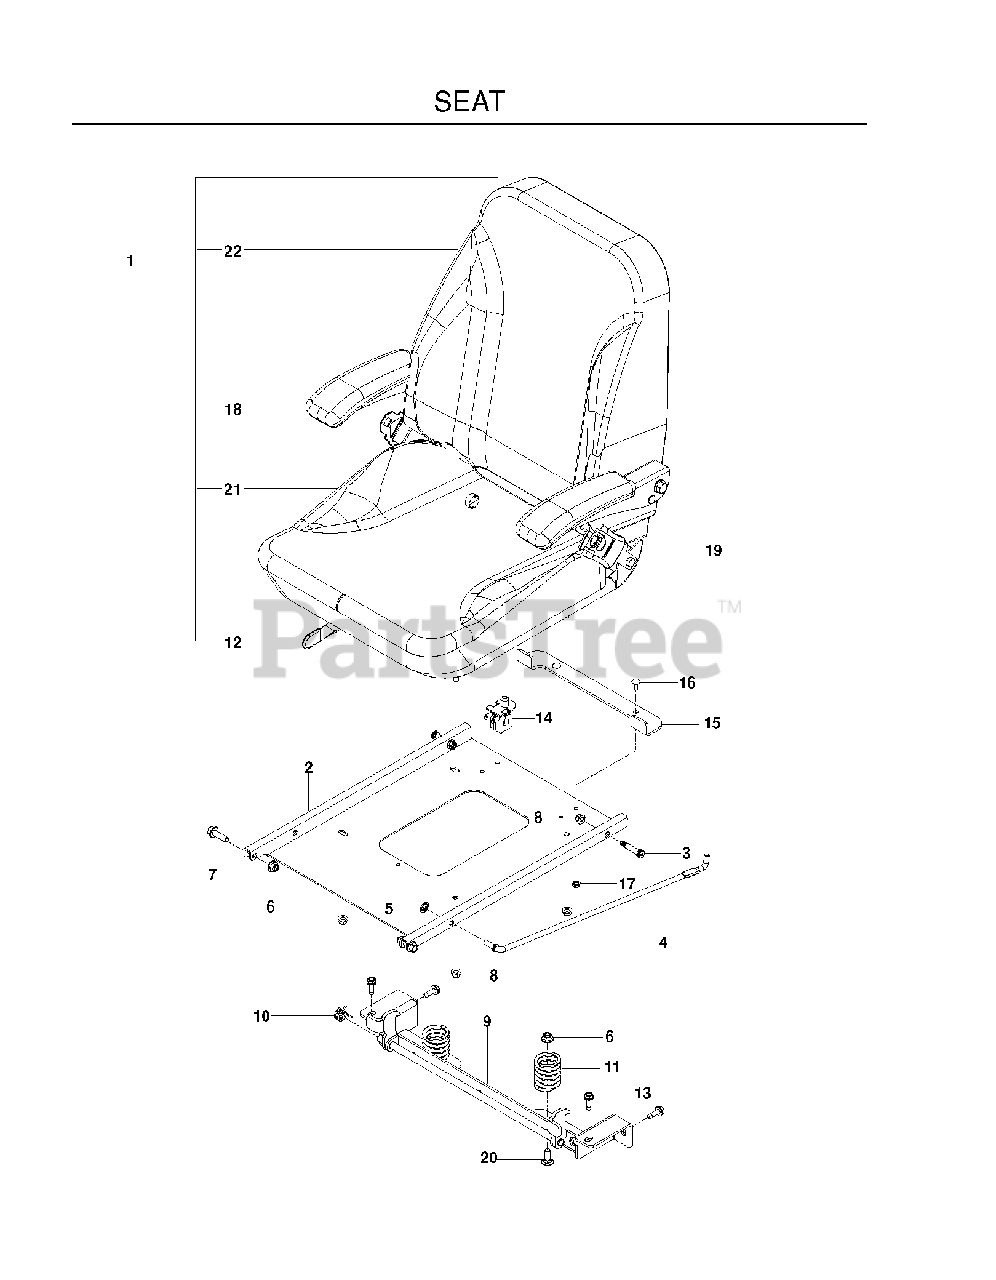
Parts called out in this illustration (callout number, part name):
1	SEAT ASSY
2	PAN, SEAT, BLACK
3	BOLT, SHOULDER 3/8 X 1.25
4	ROD, SEAT
5	BOLT RETAINER 3/8
6	NUT 3/8-16 HEX FLG NYLOC ZD
7	HHFS 3/8-16 X 1.25 GD 5
8	5/16-18 NYLOC FLANGE NUT
9	LATCH, SEAT, BLK
10	SPRING, TORSION
11	SPRING, SEAT
12	TRACK KIT
13	BLT 5/16-18 X 1 THRD FORM ZD
14	SEAT SWITCH
16	RHSSNB, 1/4-20X5/8
17	JAM NUT 1/4C
18	ARMREST, LT
20	RHSNB 3/8C X 1
21	CUSHION COVER
22	BACK COVER
